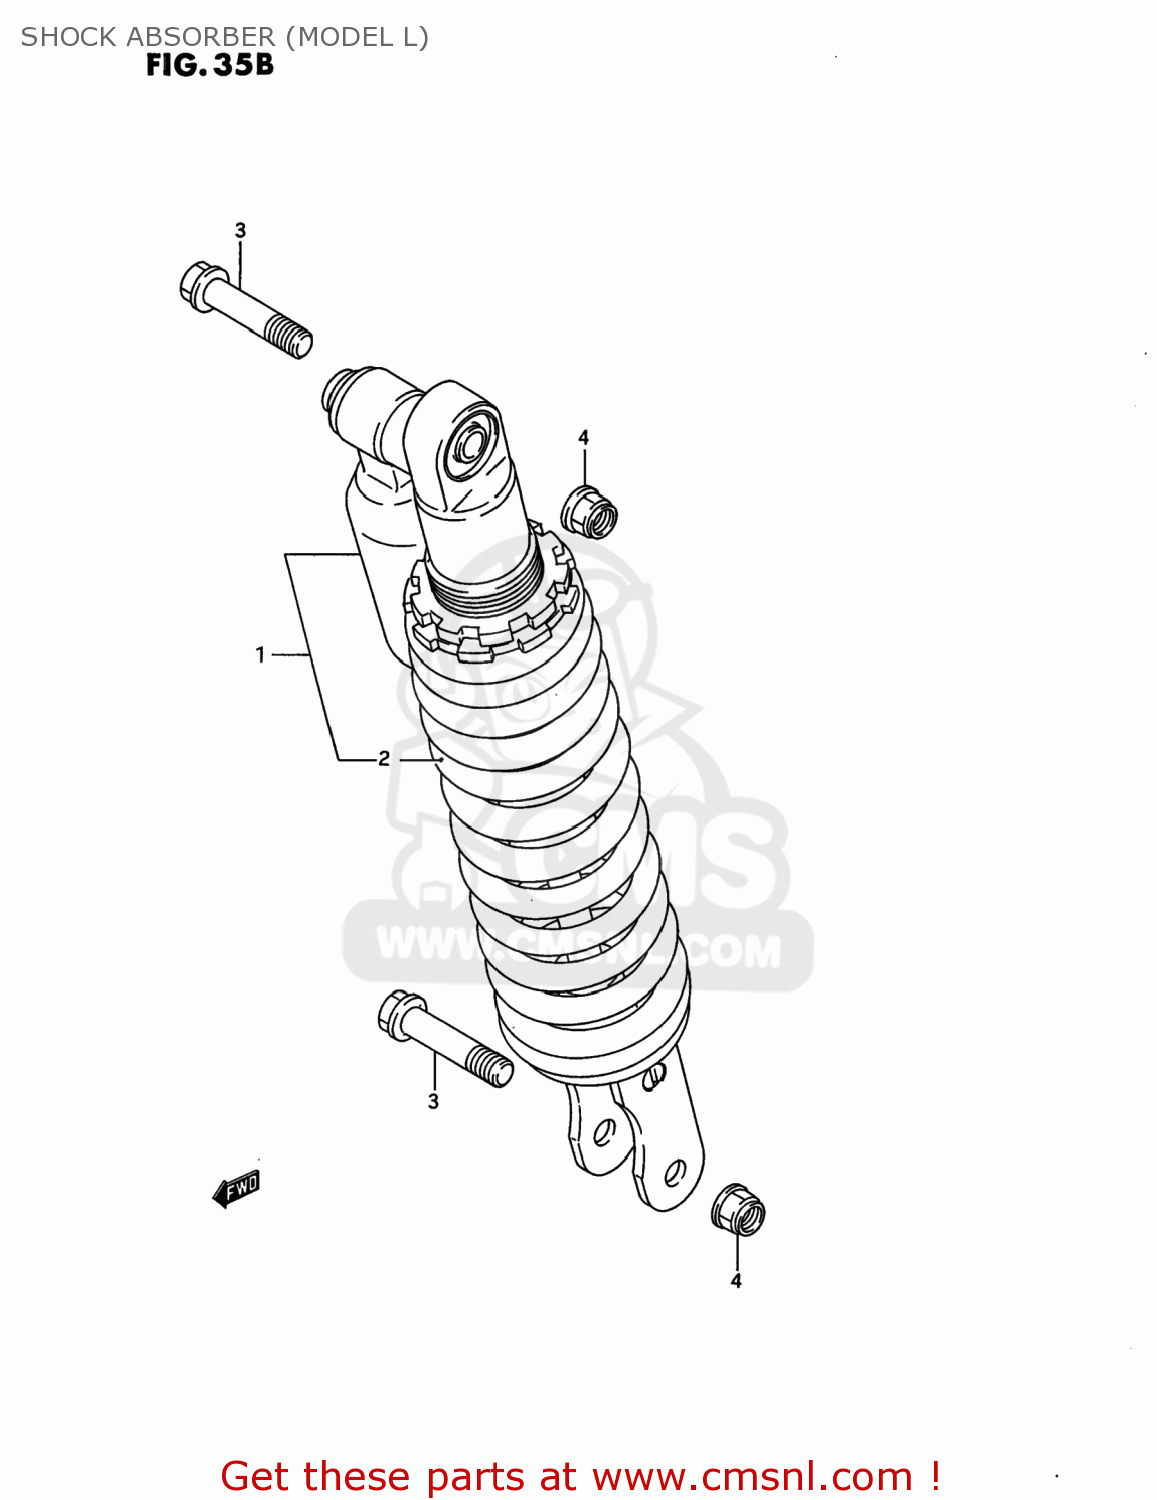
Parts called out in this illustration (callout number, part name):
1	ABSORBER ASSEMBLY,REAR SHOCK
2	SPRING
3	BOLT,RR CUSHION ROD UPR
4	NUT
